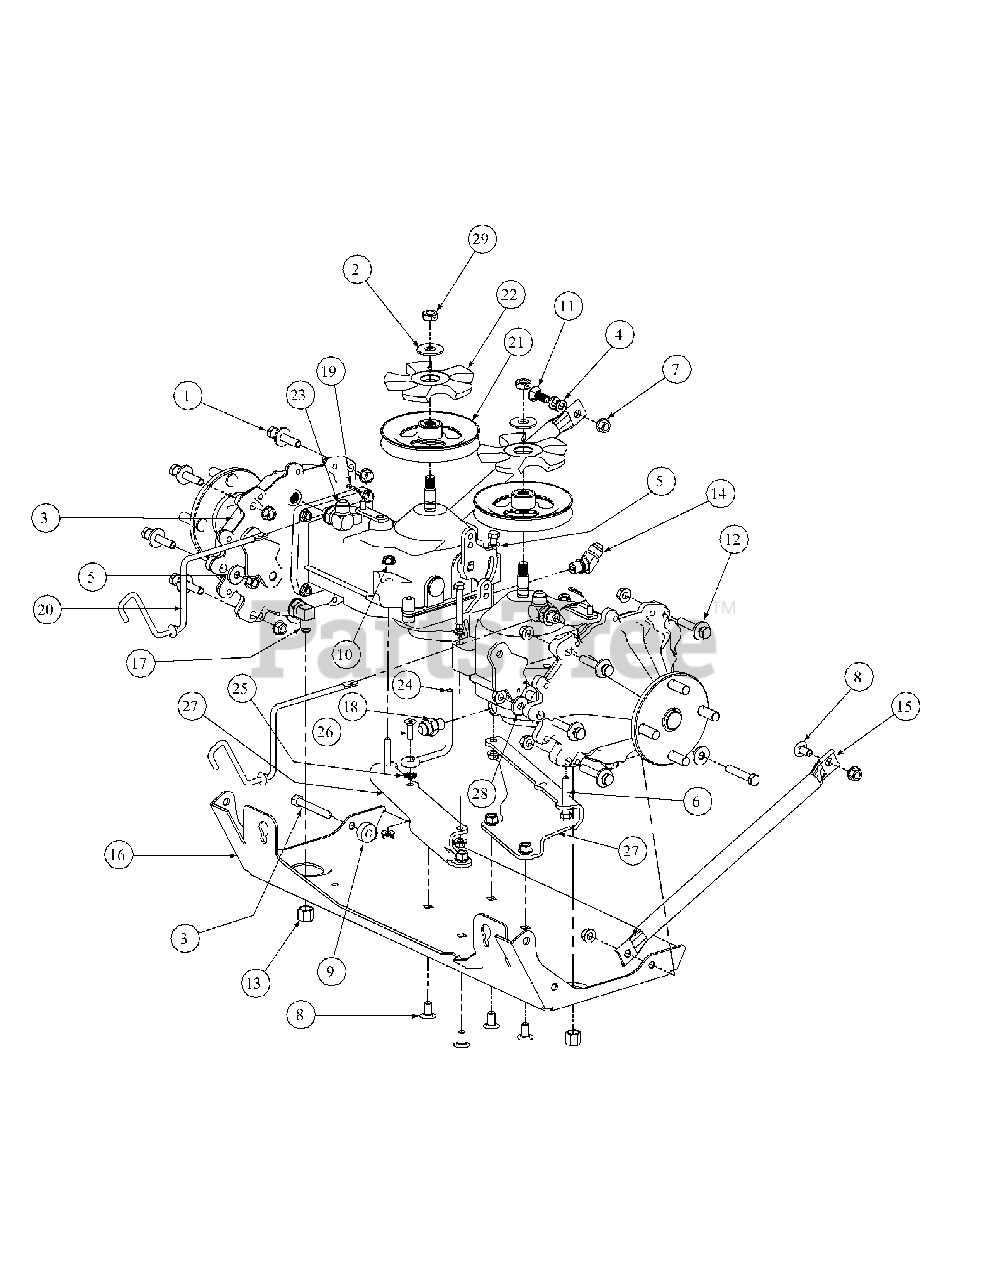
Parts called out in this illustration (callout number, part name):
1	Hex Cap Screw, 3/8-16 x 2
2	Flat Washer, 1/2
3	Hex Cap Screw, 3/8-16 x 2.5
4	Lock Washer, 3/8
5	Flat Washer, 5/16
6	Hex Cap Screw, 5/16-18 x 2
7	Flange Lock Hex Nut, 3/8-16
8	Carriage Bolt, 3/8-16 x .75 Long
9	Spacer, .406 ID x 1.00 OD x .38
10	Hex Flange Lock Nut, 5/16-18
11	Carriage Bolt, 3/8-16 x 1
12	Washer, .406 ID x 1.0 OD x .105
13	Nut Cap, 3/8
14	Elbow Fitting, 3/8 - 1/2 x 45°.
16	Skid Plate
17	Elbow Fitting, 3/8 x 3/8
18	Fitting, 1/2 x 3x8
19	Cotter Pin, .072 x 1.12 Long
20	Pump Release Rod
21	Slotted Hydro Pulley
22	Pulley Hydro Fan
23	Elbow Fitting, O-Ring 3/8, 1/2 Flare
24	Belt Guide
25	Washer
26	Screw, 5/16-18 x 1.00
27	Support Mount Bracket
28	Flat Washer, .385 x 1.0 OD x .13
29	Nut, 1/2-20, Center Lock
